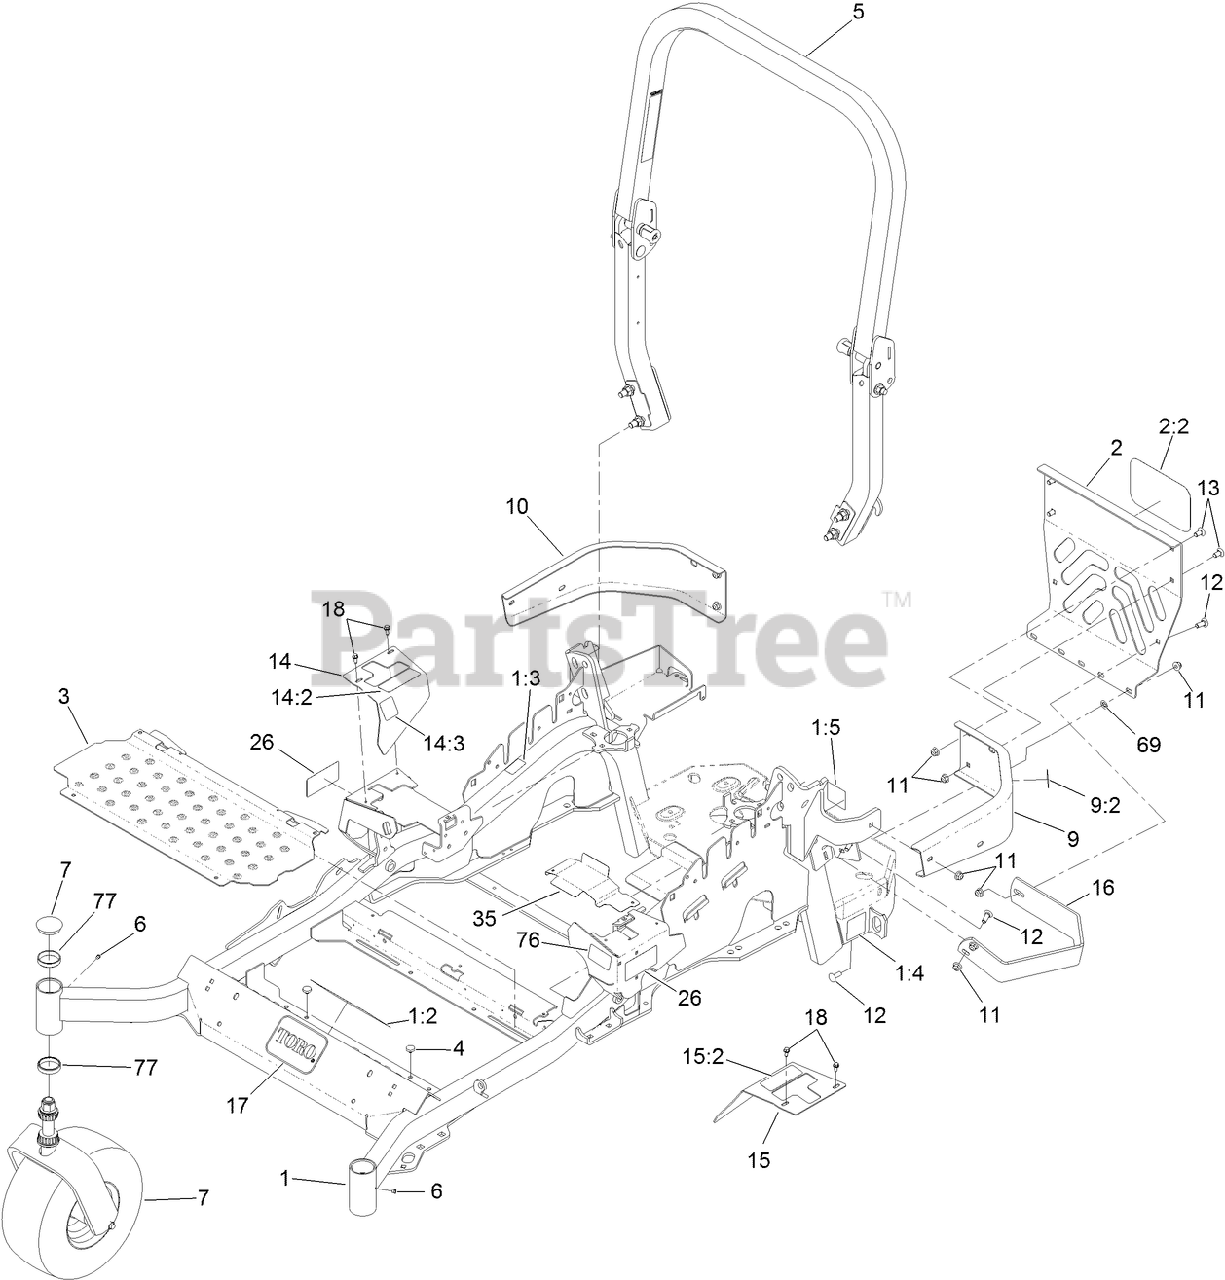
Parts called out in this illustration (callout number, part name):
1	MAINFRAME ASM
1:2	DECAL-WARNING, SLOPE
1:3	DECAL-WARNING
1:4	DECAL-HAZARD, PINCHED FINGER
1:5	DECAL-SPARK ARRESTER
2	REAR GUARD ASM
2:2	DECAL
3	FLOORPAN
4	BUMPER
5	ROPS ASM
7	Caster Wheel ASM
9	LH BUMPER ASM
9:2	DECAL-WARNING
10	BUMPER-RH
11	NUT-HF, NI
12	SCREW-CARR
13	SCREW-CARR
14	RH MOTION CONTROL COVER ASM
14:2	DECAL-CONTROL, MOTION
14:3	DECAL-PARK BRAKE, CE
15	LH MOTION CONTROL COVER ASM
15:2	DECAL-CONTROL, MOTION
16	GUARD-MUFFLER
17	DECAL
18	SCREW-HWH
35	GUARD-BELT
69	NUT-PUSH
76	DECAL-FUEL FILL, CE
77	CUP-BEARING
